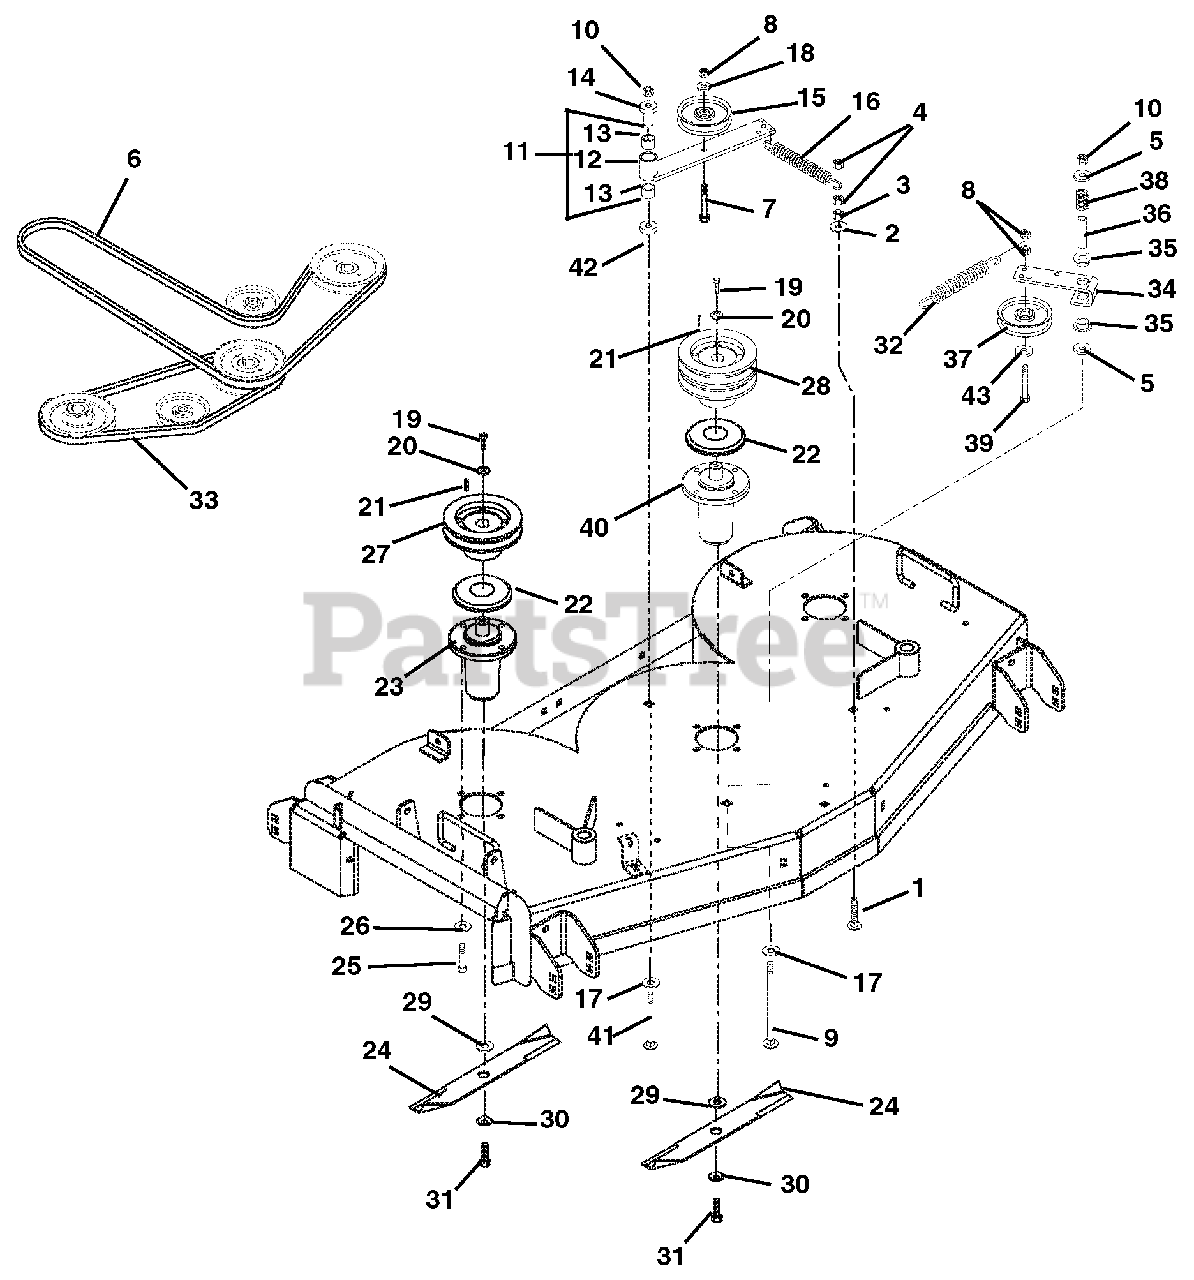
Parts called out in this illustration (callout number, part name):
1	Bolt-Round Head Square Neck .38-16 x 1.50 Grade 5
2	Washer-Locking .38 x .094 Regular
3	Nut-Hex .38-16
4	Nut-Locking-Center .38-16
5	Washer-Flat-Steel .531 x 1.25 x .10
6	V-Belt B-Section 39.38 x .65 (106, 107, 108)
7	Bolt-Round Head Square Neck .38-16 x 2.75 Grade 5
8	Nut-Locking-Center .38-16
9	Bolt-Round Head Square Neck .50-13 x 3.50 Grade 5
10	Nut-Locking-Center .50-13
11	Assembly, Idler Pivot Arm (Contains Items 12 & 13)
12	Weldment, Idler Pivot Arm
13	Bearing, 1.00 x 1.12 x .75
14	Bearing, Pedestal Powdered Metal
15	Idler-Flat 4.00 x .38 (2.00 W)
16	Spring, Extension
17	Washer-Flat-Steel .755 x 1.375 x .062
18	Washer-Flat-Steel .375 x 1.125 x .065
19	Bolt-Hex .38-16 x 1.00 Grade 8
20	Washer-Cupped-Serrated .375
21	Key-Straight .25 x 1.00 x .25
22	Slinger-Dust
23	Assembly, Maintenance Free Spindle
24	Blade- Mower (106, 107, 108, 113)
25	Bolt-Hex .38-16 x 1.00 Grade 5
26	Washer-Locking .38 x .094 Regular
27	Pulley
28	Sheave, Double (5.25)
29	Washer, Flat .64 x 1.81 x .250
30	Washer-Bellville .63 x 1.625 x .14
31	Bolt-Hex .62-18 x 1.75 Grade 8
32	Spring, Extension
33	V-Belt 5L-Section 49.97 x .672(106, 107, 108, 113)
34	Arm, Idler Pivot
35	Bushing-Flange .762 x 1.00 x .58 x 1.48 Nylon
36	Spacer .56 x .75 x 2.44 Steel
37	V-Idler, 4.00 x .38
38	Spring-Compression .085 x .80 x 1.00
39	Bolt-Hex .38-16 x 2.25 Grade 5
40	Spindle Assembly (Center)
41	Bolt-Round Head Square Neck .50-13 x 3.75
42	Washer-Flat-Steel .515 x 1.625 x .25
43	Washer-Flat-Steel .406 x .812 x .065
